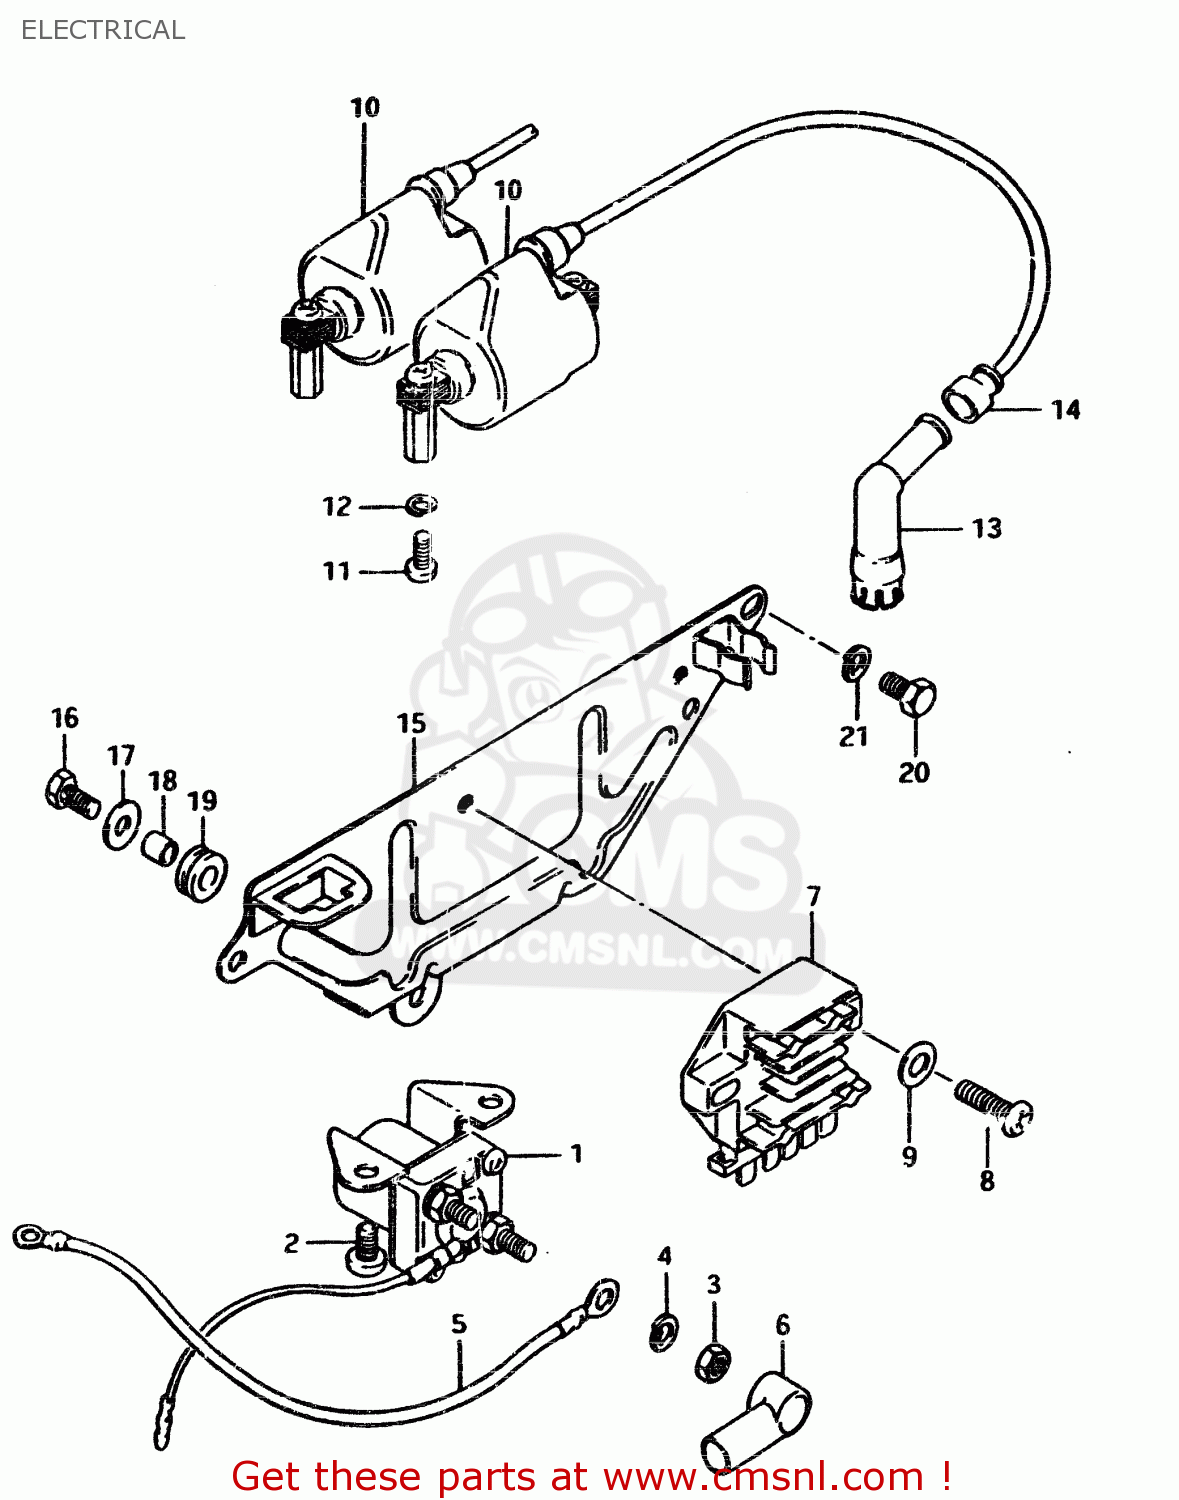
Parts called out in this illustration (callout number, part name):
1	RELAY ASSY,STARTING MOTOR
2	SCREW
3	NUT 6MM
4	LOCK WASHER
5	CORD,BATTERY MINUS
6	CAP,STARTER RELAY
7	RECTIFIER ASSEMBLY
8	SCREW
9	WASHER
10	COIL ASSEMBLY,IGNITION
11	SCREW
12	LOCK WASHER
13	CAP, SPARK PLUG (S)
14	SEAL,SPARK PLU
15	HOLDER COMP,ELECTRONIC PARTS
16	BOLT
17	WASHER
18	SPACER (6.1X8X9.5)
19	CUSHION
20	BOLT
21	LOCK WASHER
